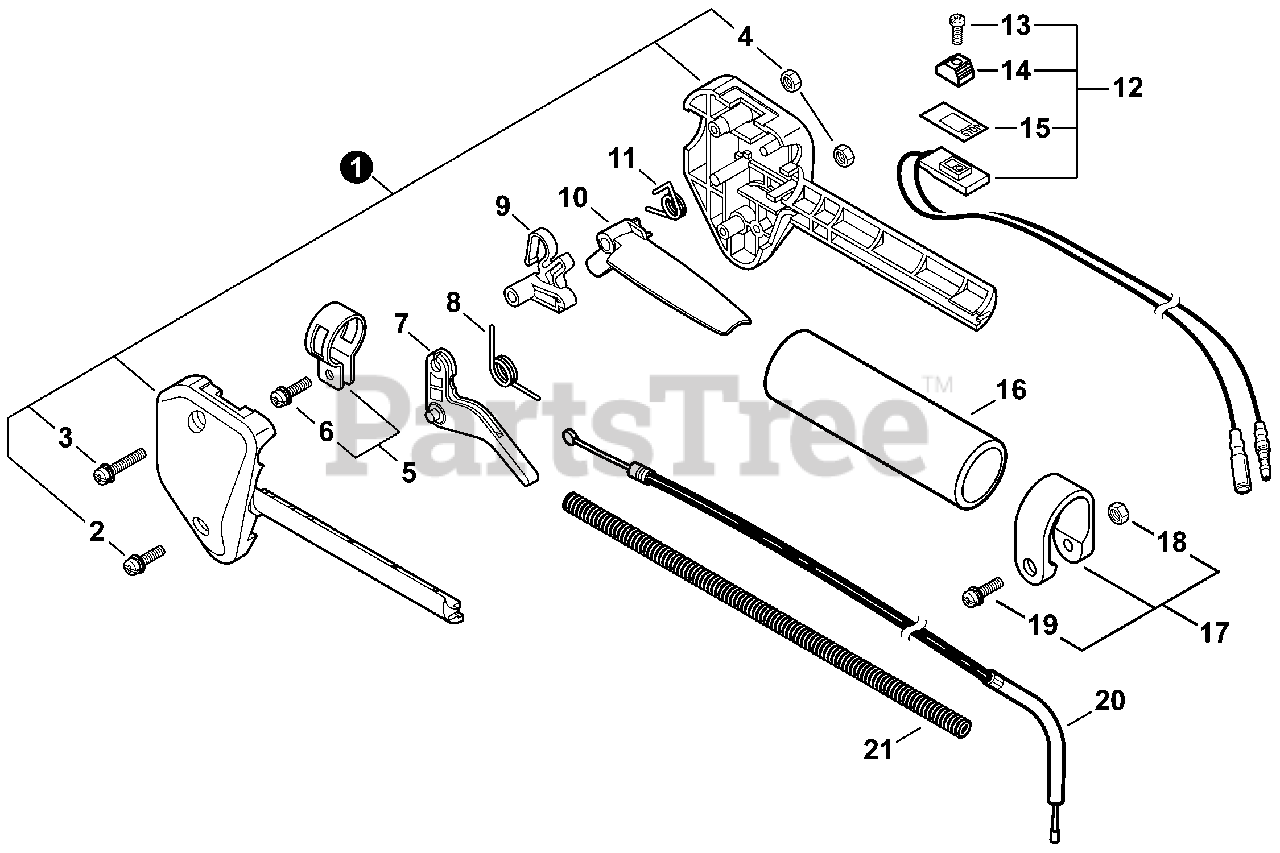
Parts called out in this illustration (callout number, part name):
1	HANDLE KIT, CONTROL
2	SCREW 5×25
3	SCREW 5×35
4	NUT M5
5	CLAMP KIT
6	SCREW 5×14
7	TRIGGER, THROTTLE
8	SPRING, TORSION
9	LOCKOUT, THROTTLE
10	LEVER, THROTTLE LOCKOUT
11	SPRING, TORSION
12	SWITCH, ON-OFF
13	SCREW 3×10
14	KNOB, SWITCH - ORANGE
15	LABEL, SWITCH
16	GRIP, HANDLE
17	CLAMP KIT
18	NUT M5
19	SCREW 5×28
20	CABLE, THROTTLE
21	TUBE, FLEXIBLE
